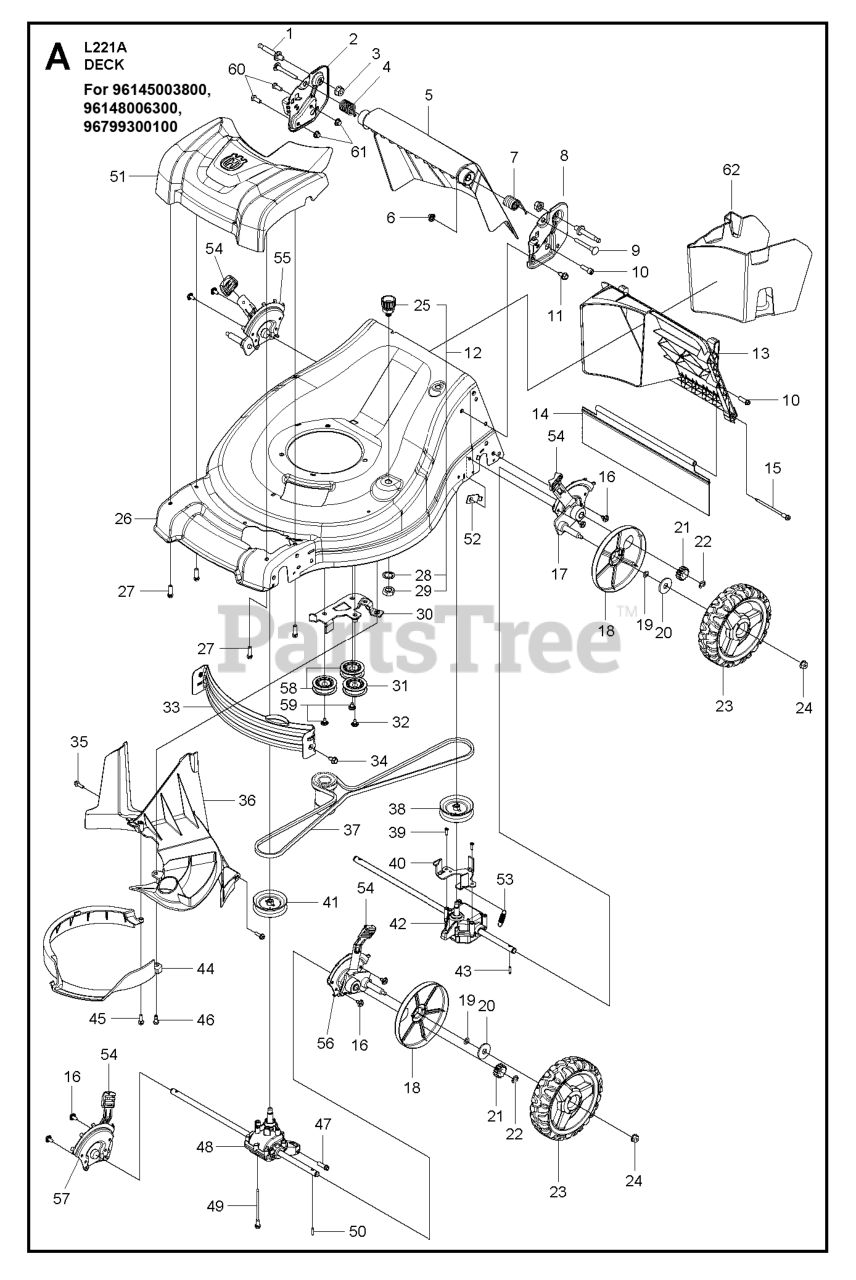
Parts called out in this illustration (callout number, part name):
1	BOLT.HAND.PIVOT.3125-18.21EFF
2	BRACKET.HANDLE.ADJ.21EF.RH.498
3	NUT.FLANGE.SERRAT.3125-18.5625
4	SPRING.RH.DOOR.21 EFF
5	DOOR REAR, 21IN EFF GRAY MS-49
6	NUT.FLANGED.3/8-16.ZINC
7	SPRING.LH.DOOR.21 EFF
8	BRACKET.HANDLE.ADJ.21EF.LH.498
9	BOLT.DOOR.PIVOT..375-16.21EFF
10	SCREW.HI-LO,5/16-14 X T-45
11	BOLT.5/16HEX.WHS.HD
12	KIT.WASH-OUT.PORT
13	BAFFLE ASSY, 21 EFF
13	INSERT.REAR.21 EFF
14	SKIRT.REAR.21 EFF
15	SCREW.HI-LO.5/16-14 X 4.10
16	SCREW
17	ADJUSTER.4PT.21EFF.RF/LR.BLK
18	COVER.DUST.WHEEL.INNER.WALK
19	O-RING..070X.487.NEOPRENE
20	WASHER FLUT
21	PINIION.14.TOOTH.RGD
22	E-RING 7/16 RE
23	WHEEL.8".AWD.3SP.EXT.DR.GREY
24	NUT.HEX.FLANGE.3/8-16.LO(3 2)
25	FITTING, HOSE, WATER WASHOUT
26	KIT.HSG.21EFF.AWD.WO.668.CE SY
27	SCREW.HI-LO. 5/16 X 1.00
28	WASHER.LOCK.INTERNAL.TOOTH
29	LOCKNUT.HEX.WITH.O-RING
30	BRACKET.ASM.IDLR.AWD.21EFF.BZP
31	PULLEY IDLER AWD, RWD WITHOUT
31	PULLEY.RWD.IDLER.DBL SEAL
32	SCREW
33	BAFFLE.FRONT.21 EFF
34	BOLT.5/16HEX.WHS.HD
35	SCREW.HI-LO.13-16X.750.375XDRV
36	COVER.BELT/REAR BAFFLE.21 EFF
37	BELT.DRIVE.21EFF.AWD
38	PULLEY.DRIVE.SM.AWD/RWD
39	SCREW
40	BRACKET.TRAN.BELTKEEPER.22+RGD
41	PULLEY.DRIVE.SM.AWD/RWD
42	TRANSMISSION.AWD.REAR.21EFF
43	PAWL, DRIVE
44	RING.STRIPPER.21 EFF
45	SCREW.HI-LO.13-16X.750.375XDRV
46	BOLT SHOULDER_1/4-20_TRILOB
47	SCREW.HI-LO. 5/16 X 1.00
48	TRANSMISSION.AWD.FRONT.21EFF
49	SCREW.HI-LO.5/16-14 X 4.10
50	PAWL, DRIVE
51	COVER.DR.FULL.HUSQ.21EFF.AWD
52	STRAP.PLATE ATTACH.21 EFF.GLV
53	SPRING.RETURN.AUTO.
54	SELECTOR KNOB
55	ADJUSTER.4PT.21EFF.LF/RR.BLK
56	ADJUSTER.4PT.21EFF.LF/RR.BLK
57	ADJUSTER.4PT.21EFF.RF/LR.BLK
58	PULLEY IDLER AWD, RWD WITH SPA
58	PULLEY.ASM.22+ AWD
60	BOLT.FIN.HEX.5/16-18X3/4
61	NUTNYLOK.FLRANGE.5/16-18
62	PLUG.MULCH.21 EFF
